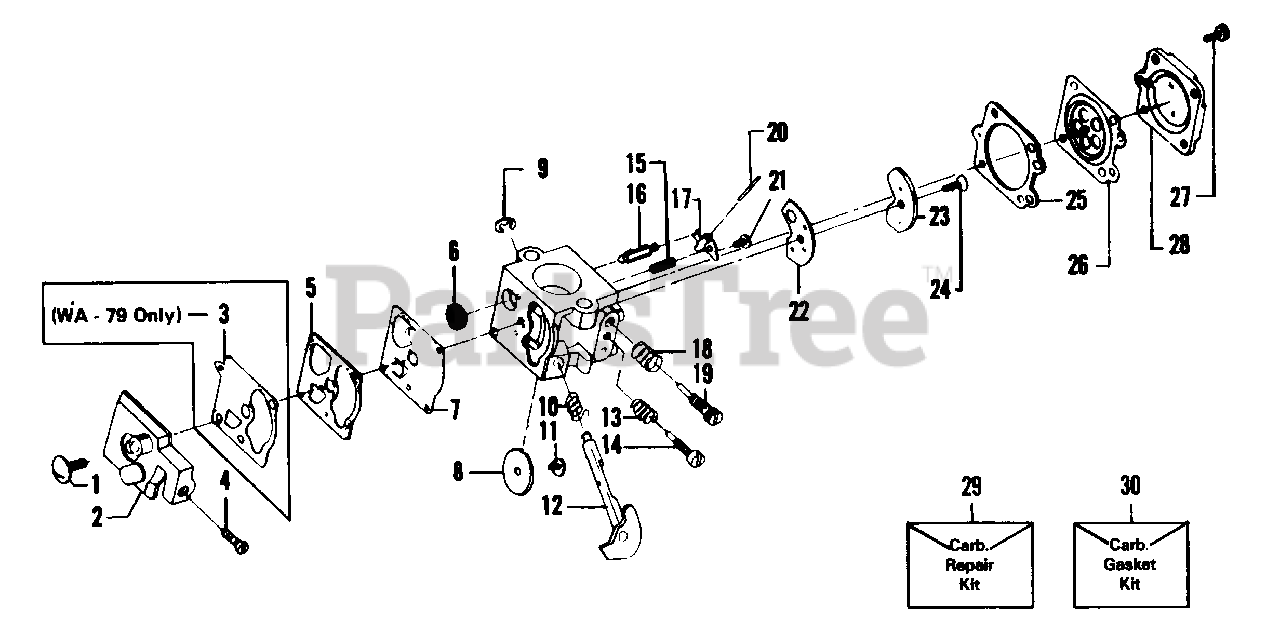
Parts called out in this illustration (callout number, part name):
1	Screw - Pump Cover
2	WA - 149 (#35183)
3	Diaphragm - Pump (WA - 79 Only -
4	Screw - Idle Adjustment
5	Gasket - Pump
5	WA - 149 (#35183)
6	Screen - Inlet
7	Diaphragm - Pump
7	WA - 149 (#35183)
8	Valve - Throttle
9	Clip - Throttle Shaft
10	Spring - Throttle Return
11	Screw - Throttle Valve
12	Shaft Assembly - Throttle
13	Spring - Idle Needle
14	Needle - Idle
15	Spring - Metering Lever
16	Valve - Inlet Needle
17	Lever - Metering
18	Spring - Hi Speed Needle
19	Needle - Hi Speed
20	Pin - Metering Lever
21	Screw - Metering Lever Pin
22	Gasket - Circuit Plate
23	Plate - Circuit
24	Screw - Circuit Plate
25	Gasket - Metering Diaphragm
26	Diaphragm Assembly - Metering
27	Screw - Assembly - Metering Cover & Throttle Shaft Clip
28	Cover - Metering Diaphragm
29	Kit Carb - Kwik Repair Kit
29	WA - 149 (35183)
30	Kit Carb - Gasket/Diaphragm
30	WA - 149 (#35183)
